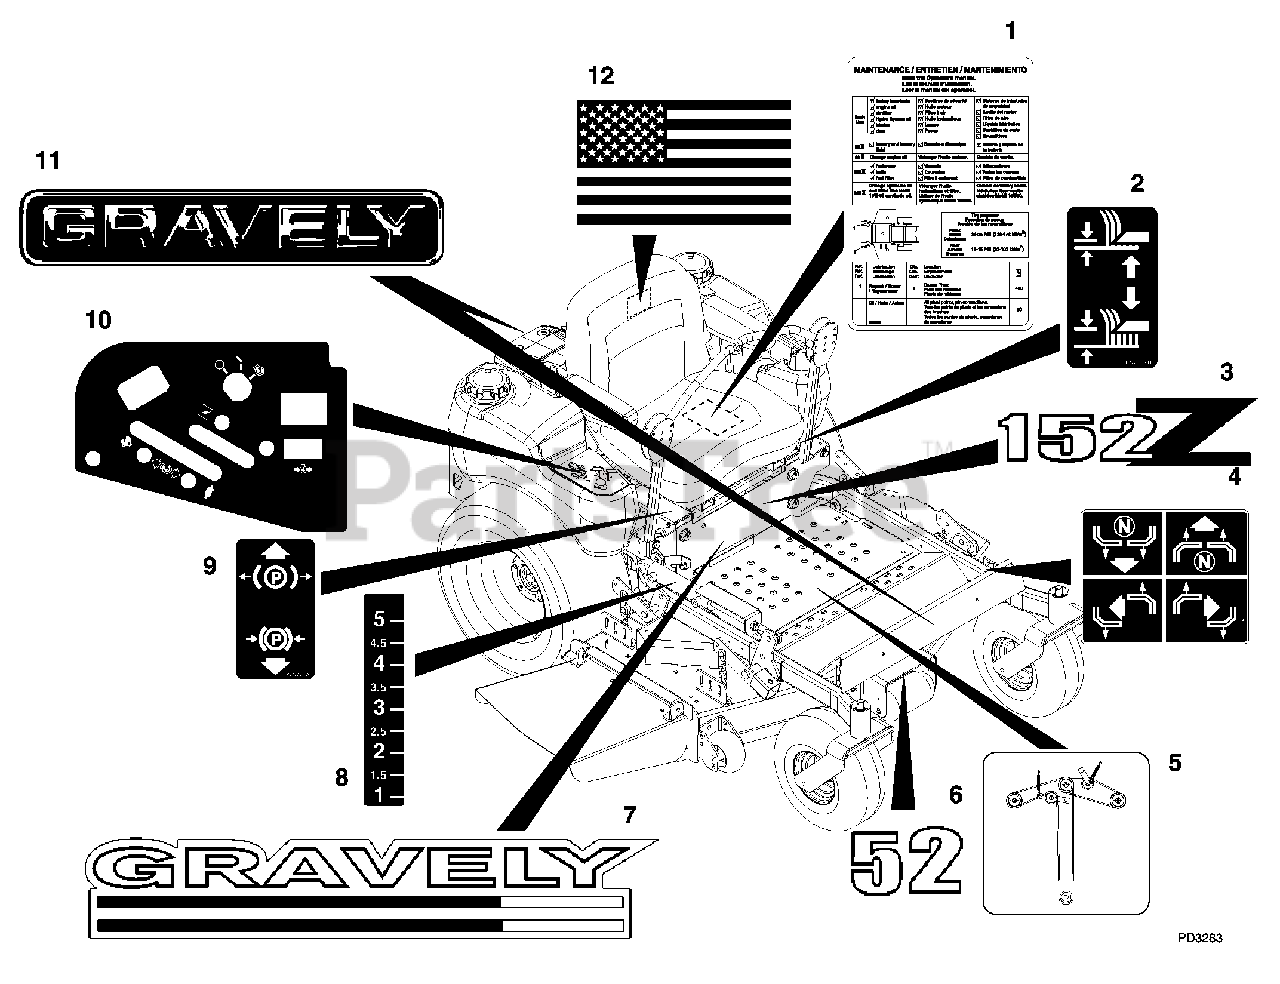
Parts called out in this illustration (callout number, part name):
1	Decal, Service Instructions
2	Decal, Lift Lever
3	Decal, PM 152Z (044, 054)
3	Decal, PM 144Z (042)
3	Decal, PM 148Z (043)
3	Decal, PM 160Z (051, 055)
4	Decal, Instructional Steering
5	Decal, Belt Diagram
6	Decal, 52 (044, 054)
6	Decal, 44 (042)
6	Decal, 48 (043)
6	Decal, 60 (051, 055)
7	Decal, ZT Hood
8	Decal, Height of Cut
9	Decal, Parking Brake Lever
10	Decal, Control Panel
11	Decal, 15" Gravely Logo
12	Decal, American Flag
